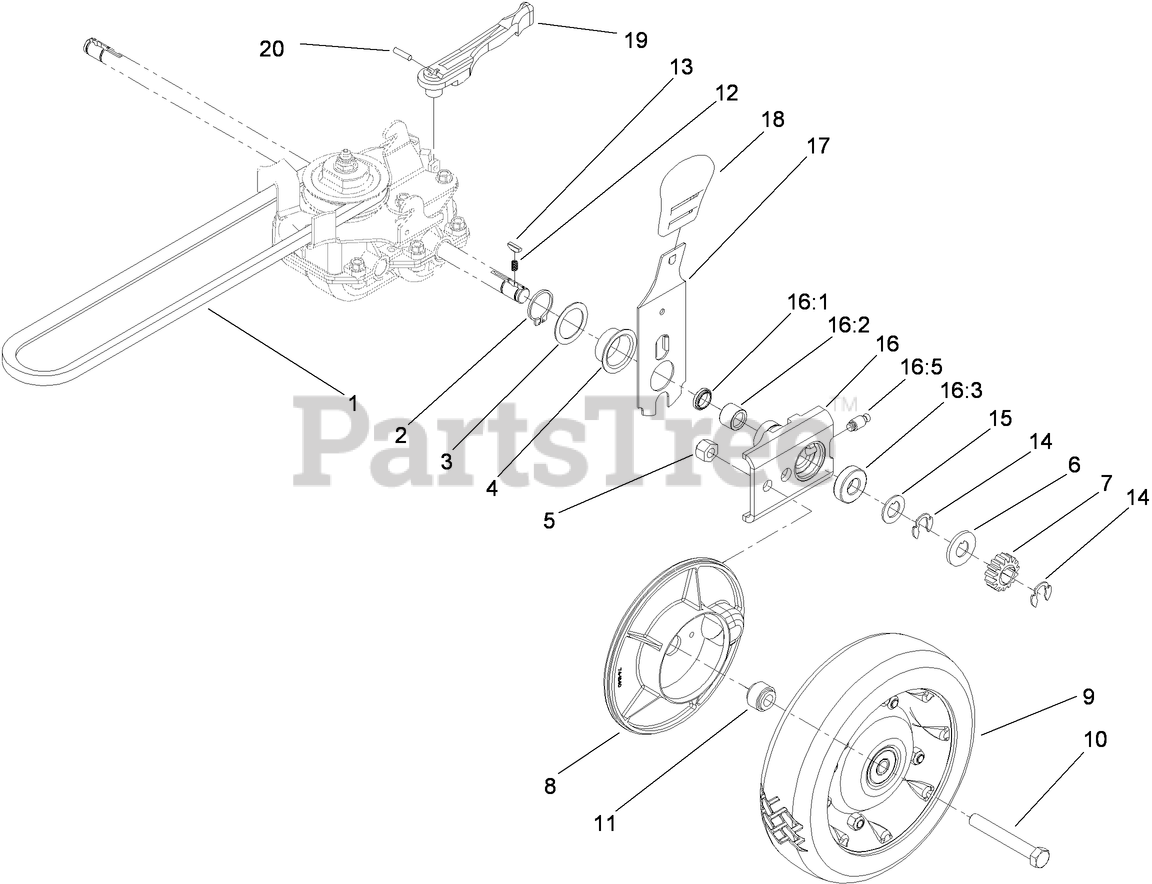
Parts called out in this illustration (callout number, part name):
1	V-BELT
2	RING-RETAINING
3	WASHER
4	CAP-END
5	NUT-LOCK, CONE
6	WASHER-THRUST, OUTER
7	GEAR-PINION
8	COVER-WHEEL
10	SCREW-HH
11	SPACER-COVER, WHEEL
12	SPRING-COMPRESSION
14	RING-RETAINING
15	WASHER-THRUST, OUTER
16	PIVOT ARM ASM
16:1	SEAL-OIL
16:3	BEARING-WHEEL
17	REAR SPRING ARM ASM
18	KNOB-HOC
19	LEVER-SHIFT
20	PIN-SPRING
